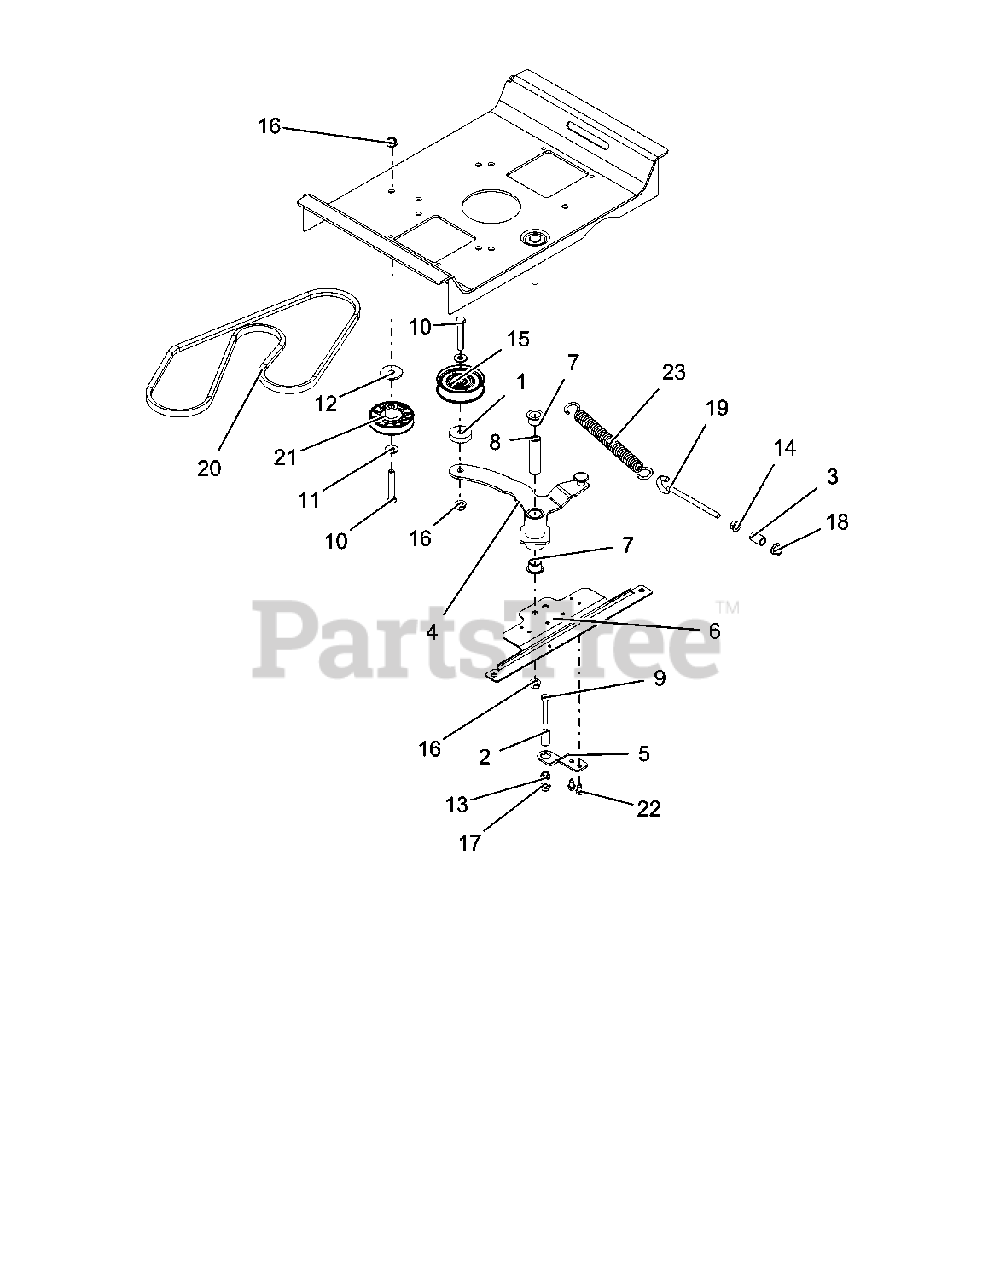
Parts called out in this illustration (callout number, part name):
1	SPCR, .39X1.50X.380
2	SPCR, RUBBER 5/16 ID X 1.0 LG
3	SPCR, .375X.625X.970
4	WLDMT, IDLER GROUND DRIVE
5	BRKT, CLUTCH STOP
6	BRKT, DRIVE IDLER MTG
7	BSHG, FLANGE 0.75 X 0.875 X 0.625 X 0.125
8	BSHG, SLV .380x.750x2.53
9	BLT-HEX .31-18X2.00 GR5 YWZC
10	BLT-HEX .38-16X2.25 GR5 YWZC
11	WSHR-FL-STL.38X.875X.083 YWZC
12	WSHR-FL-STL .380X1.50X.125 YWZC
13	@NUT-SPNLK-FLG .312-18 YWZC
14	@NUT-SPNLK-FLG .375-16 YWZC
15	IDLER, FLAT - 3.05" X .75"
16	NUT, LK-TOP-FLG .38-16 YWZC
17	NUT, LK-TOP-FLG .312-18 YWZC
18	NUT-LK-NYL-FLG .38-16 YWZC
19	BOLT, EYE .38-16X6.00 .62 DIA
20	V-Belt, A-RAW EDGE
21	IDLER, V 3.00" COMPOSITE
22	SCR-TAP .25-20X.50 HWH TR YWZ
23	SPRG, EXTENSION - SWIVEL
